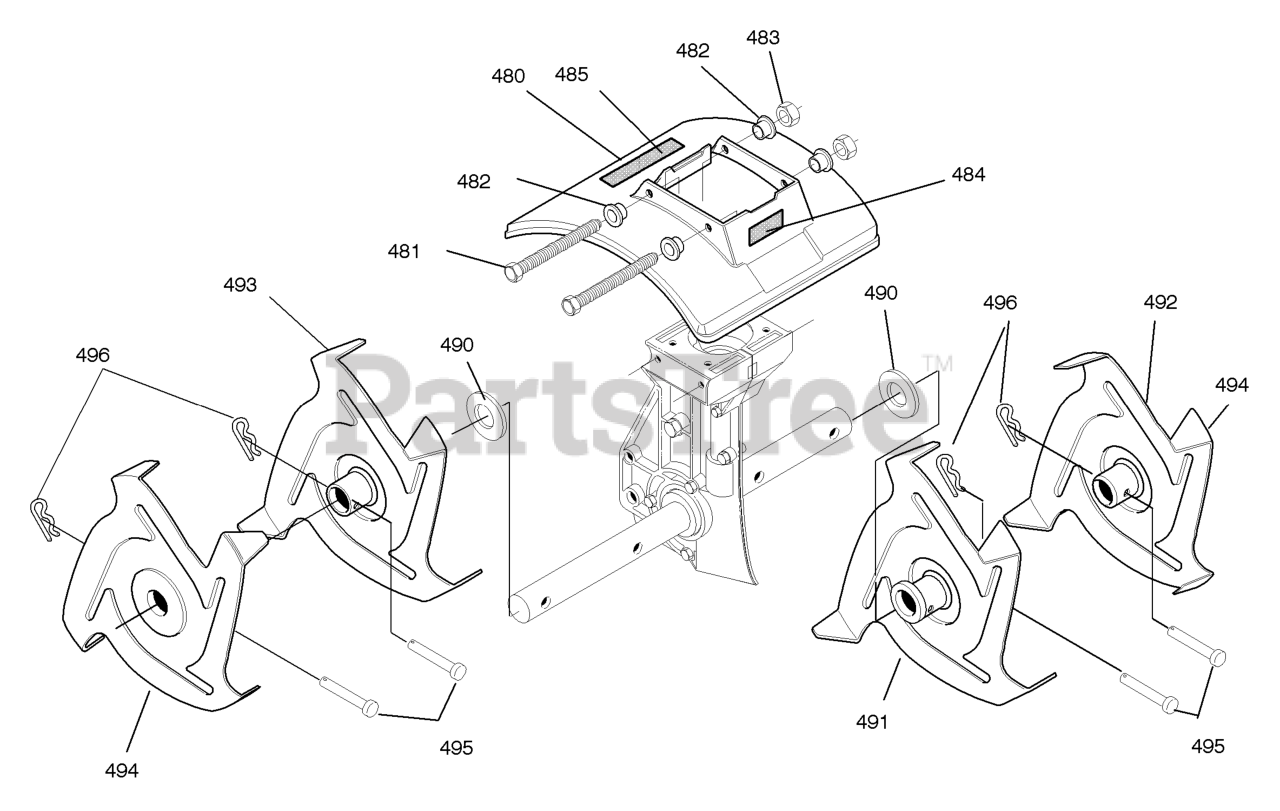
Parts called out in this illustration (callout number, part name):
480	Shield, Tine
481	Screw, 1/4-20X5.50
482	Spacer, Flange
483	Nut, 1/4-20
484	Decal, Murray
485	Decal, Caution
490	Washer, Felt
491	Tine Assy. Inner LH
492	Tine Assy. Outer LH
493	Tine Assy. Inner RH
494	Tine Assy. Outer RH
495	Clevis Pin
496	Hair Pin
